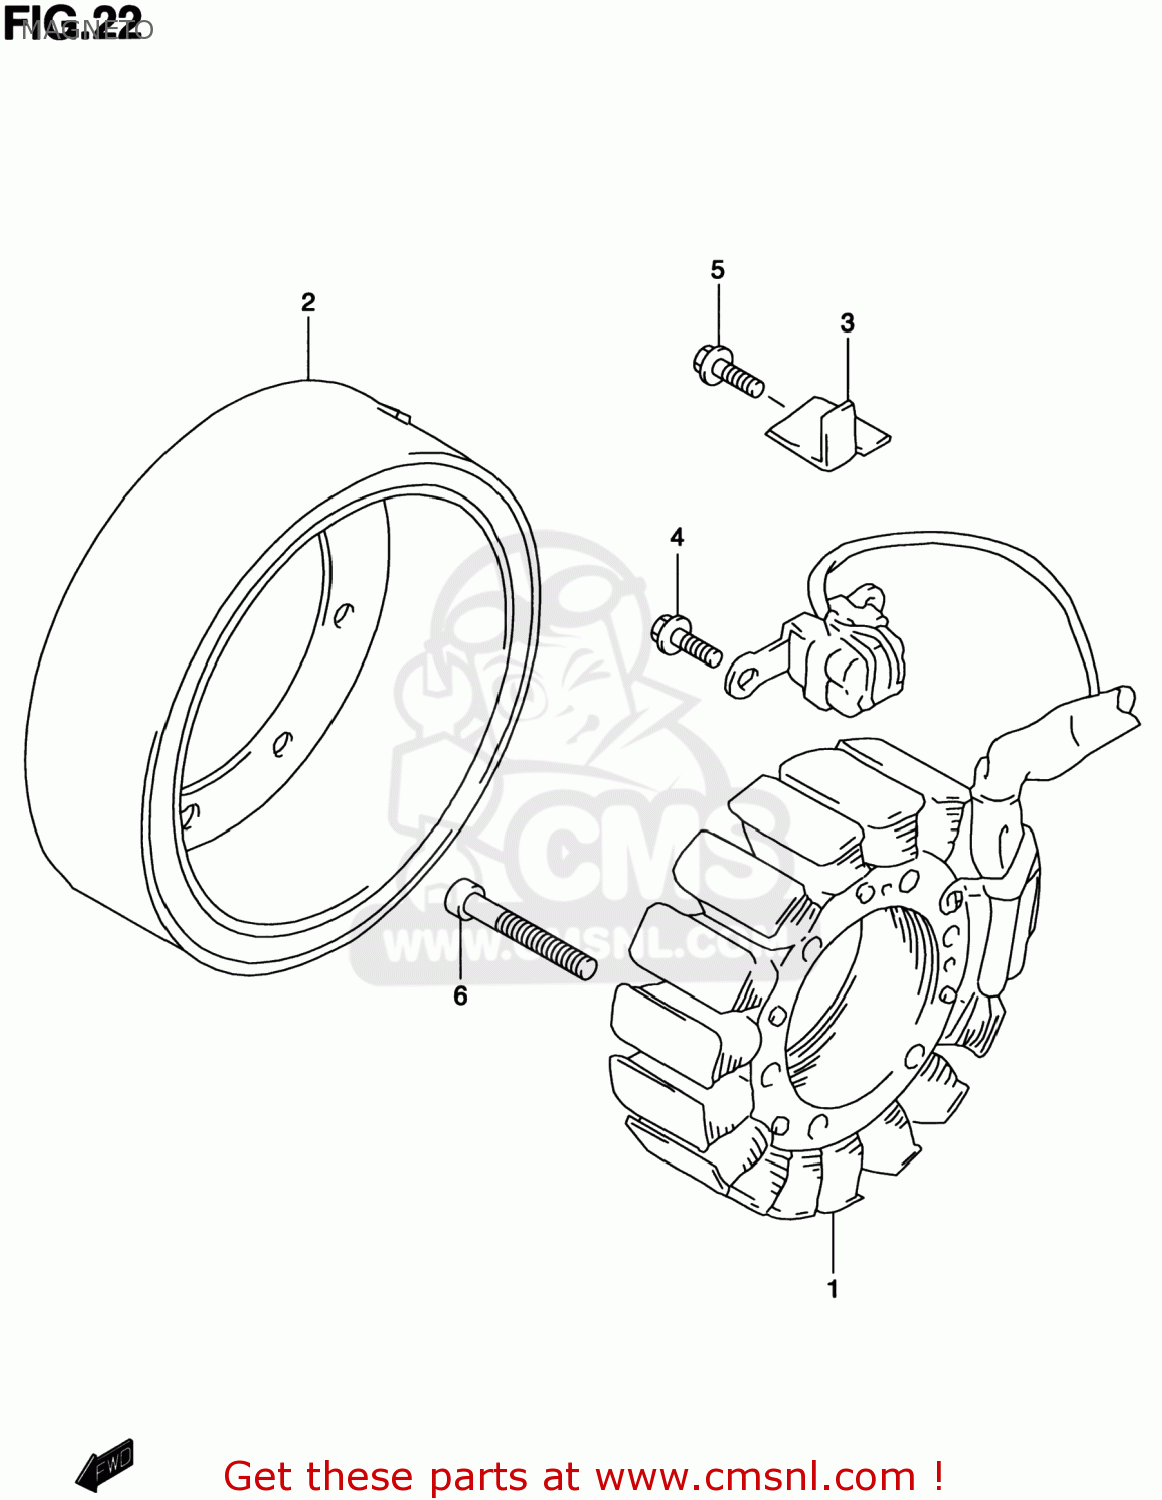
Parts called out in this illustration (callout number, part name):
1	STARTER ASSY
2	ROTOR ASSY
3	CLAMP,MAGNETO LEAD NO.1
4	BOLT
5	BOLT
6	BOLT
